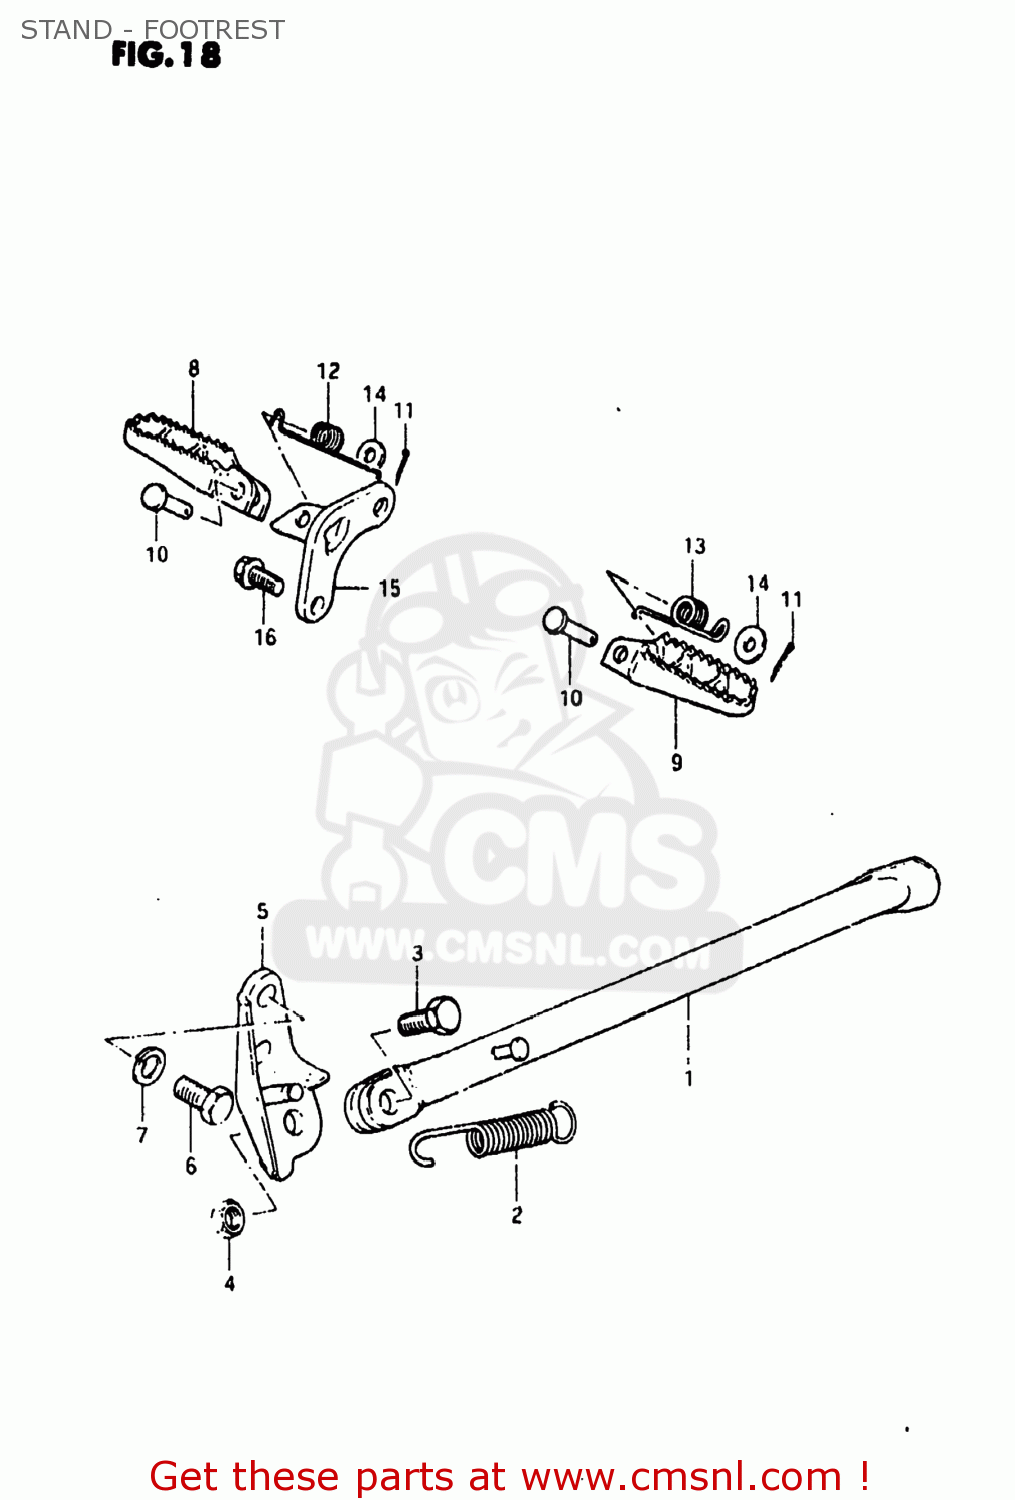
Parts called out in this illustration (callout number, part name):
1	STAND,SIDE
2	SPRING
3	BOLT(10X30)
4	NUT
5	BRACKET,PROP STAND
6	BOLT(10X19)
7	LOCK WASHER
8	RUBBER,FRONT FOOTREST
9	FOOTREST
10	PIN
11	PIN 20X20
12	SPRING
13	SPRING
14	WASHER
15	HOLDER,FRONT FOOTREST,RIGHT
16	BOLT(10X20)
